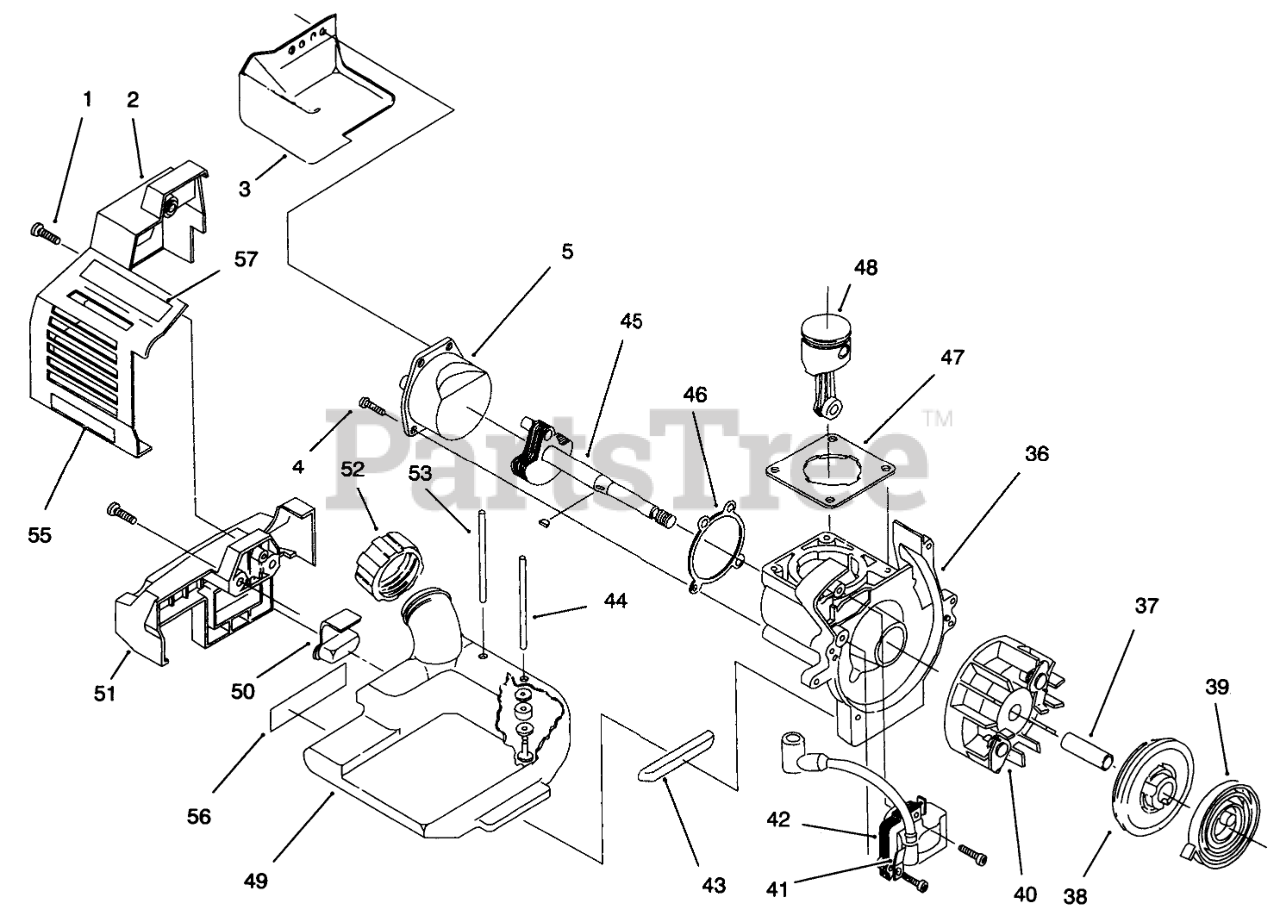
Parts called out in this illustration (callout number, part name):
1	CLUTCH COVER SCREW ASM
2	REAR COVER
3	HEAT SHIELD
4	MOUNTING SCREW SET
5	CRANKCASE CAP
36	Crankcase Asm. (Incl. Ref. #5, 45-46)
37	SPACER
38	RECOIL PULLEY
39	RECOIL SPRING
40	FLYWHEEL
41	GROUND TAB
42	MODULE ASM
43	FRONT FUEL TANK PAD
44	FUEL LINE ASM
45	POWER SHAFT ASM
46	CRANKCASE CAP GASKET
47	CYLINDER GASKET
48	PISTON & ROD ASM
49	FUEL TANK ASM
50	REAR FUEL TANK PAD
51	FUEL TANK BRACKET
52	FUEL TANK CAP
53	FUEL RETURN LINE
55	Decal-Warning
56	Decal-Fuel & Oil Mix
57	DECAL - CARBURETOR
